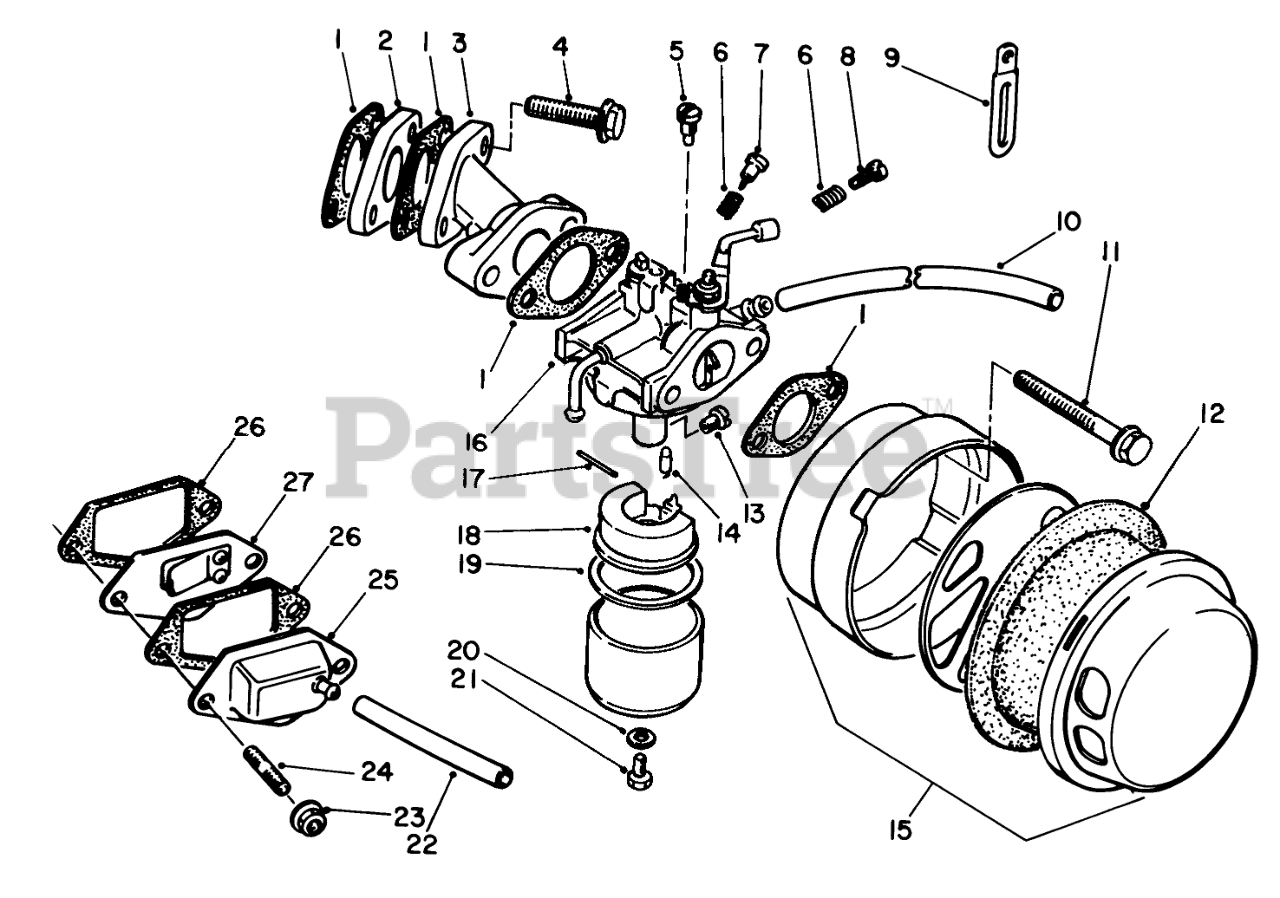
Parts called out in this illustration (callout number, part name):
1	GASKET
2	Insulator
5	Jet
6	SPRING
7	ADJUSTER
8	SCREW
9	CLAMP
10	Hose-Overflow
11	Screw-Hex Flange Hd.
12	FILTER FOAM
13	Jet-Main
14	NEEDLE ASSM.
15	Air Cleaner Assembly
16	Carburetor Assembly (Incl.Items #13, 14, 17-21)
17	Pin
18	Float
19	GASKET
20	GASKET
21	Screw-Hex Hd.
24	Bolt-Stud
25	Cap-Breather
26	Gasket
27	REED VALVE
